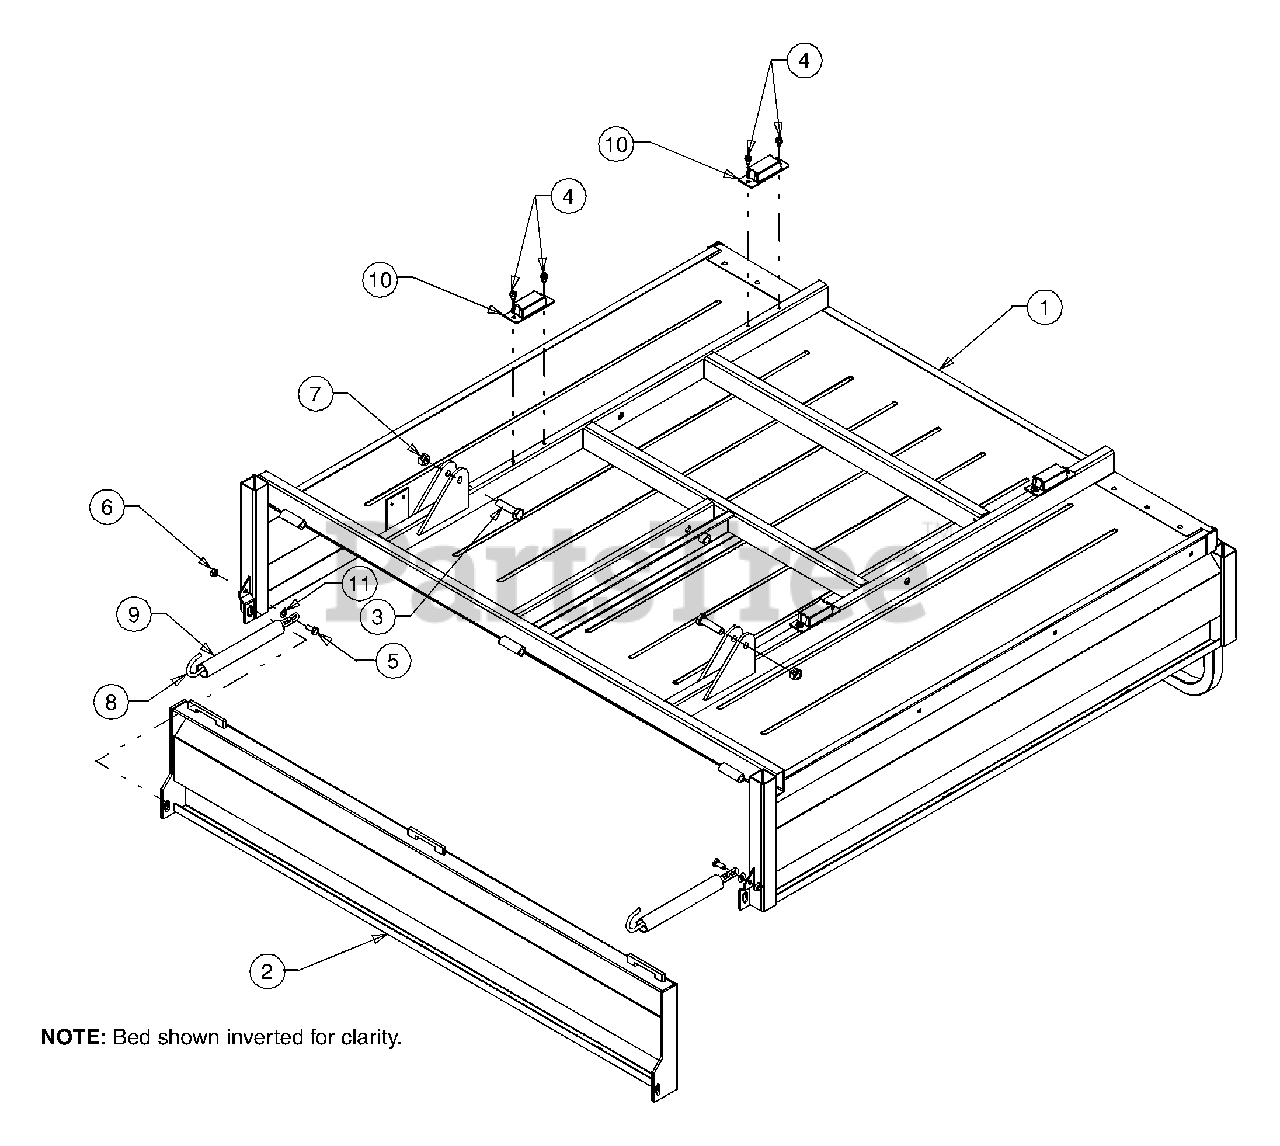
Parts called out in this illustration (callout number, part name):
1	Bed Assembly, Utility
2	Tailgate Assembly
3	Screw, Hex, 1/5-13 x 2.0, Gr5
4	Screw, Self-tapping, 1/4-20 x 0.500
5	Screw, Hex, 5/16-18 x .75, Gr5
6	Nut, Hex, 5/16-18, Gr5
7	Nut, Hex Lock, 1/2-13
8	Chain, Tailgate
9	Cover Cloth, Tailgate Chain
10	Bumper, Extension Suspension
11	Washer, Flat, .33 x .678 x .030
